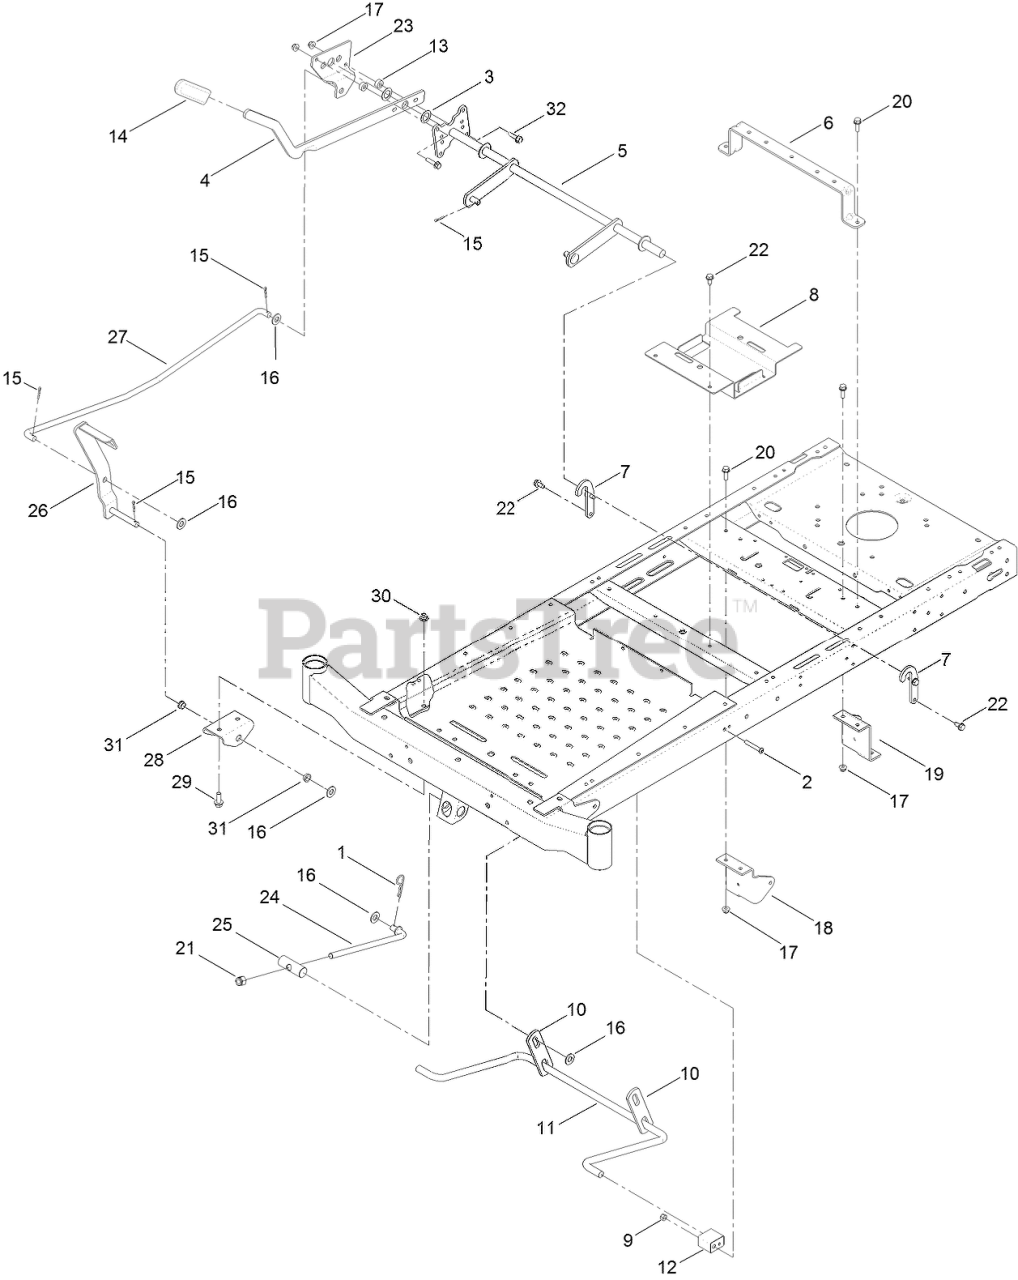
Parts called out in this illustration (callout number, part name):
1	PIN-COTTER
2	SCREW-HSBH
3	WASHER-THRUST
4	LEVER-LIFT
5	LIFT-DECK, WIDE
6	BRACE-SEAT, REAR
7	BRACKET-LIFT
8	BRACKET-BATTERY
9	NUT-LOCK, NI
10	LINK-LIFT
11	ARM-LIFT, REAR (WIDE)
12	BLOCK-PIVOT
13	SPACER
14	GRIP-LEVER
15	PIN-COTTER
16	WASHER-FLAT
17	NUT-HF, NI
18	MOUNT-HYDRO, FRONT (RH)
19	MOUNT-HYDRO, FRONT (LH)
20	SCREW-HHF
21	NUT-HEX
22	SCREW-HWHTF
23	PLATE-FOOTLIFT
24	ROD-TRUNION
25	PIN-PIVOT
27	ROD-FOOTLIFT
28	BRACKET-FOOTLIFT
29	SCREW-HHF
30	NUT-HF, NI
31	BUSHING-FLANGE
32	SCREW-HHF
